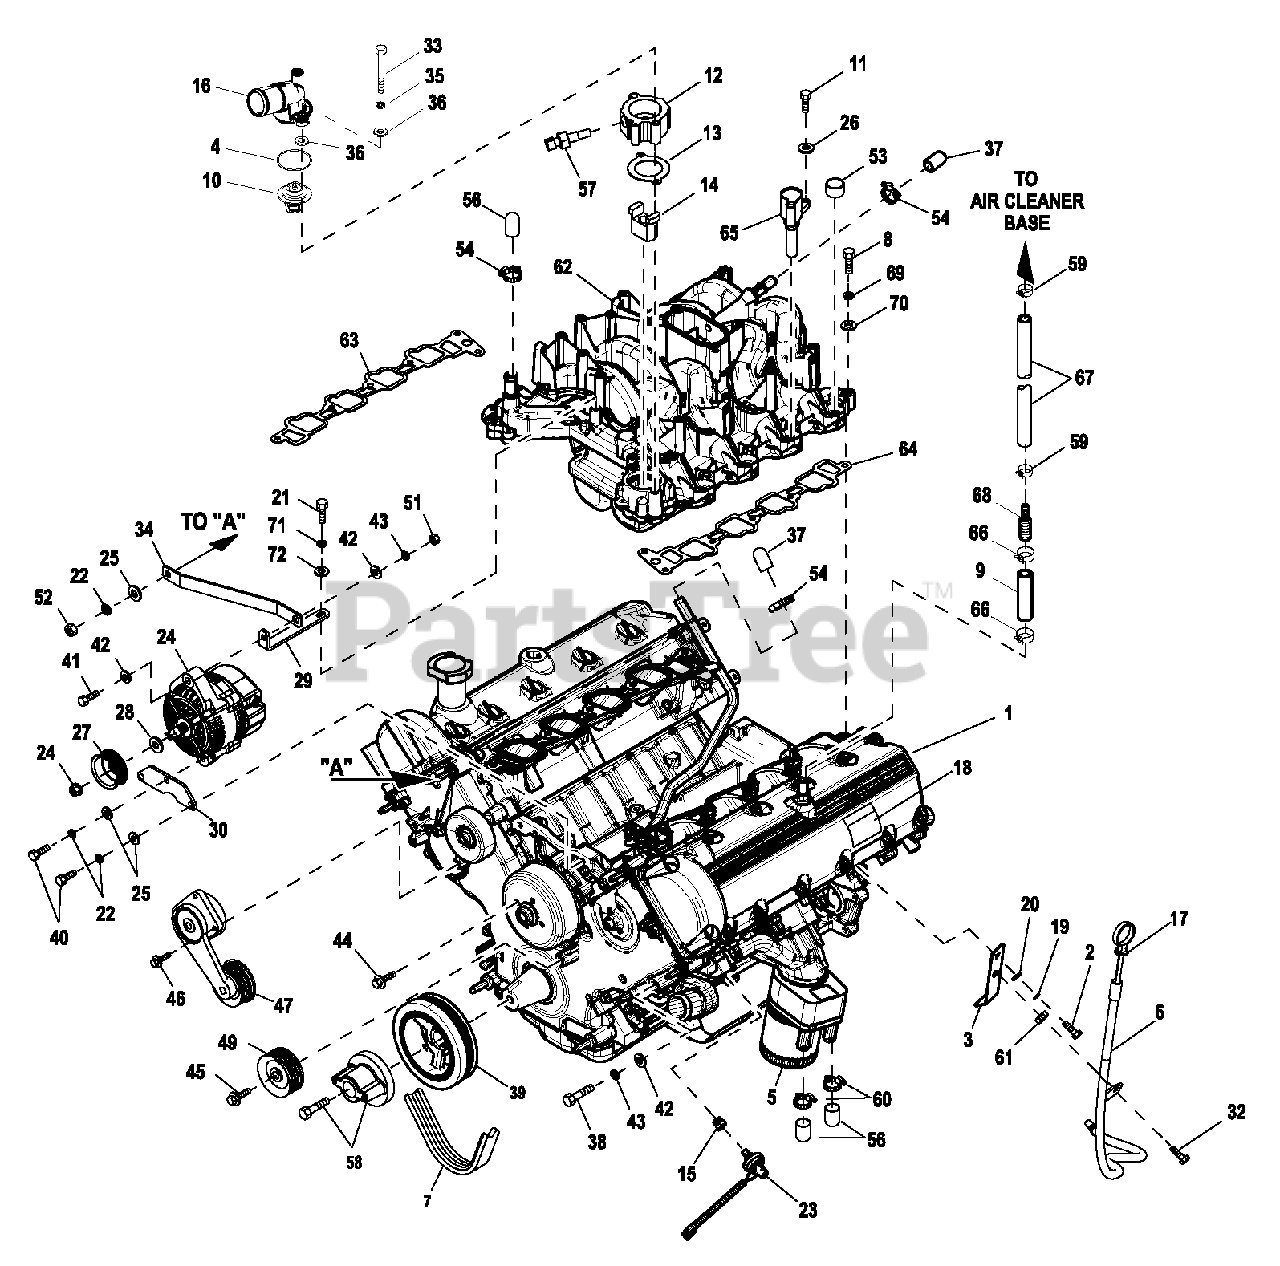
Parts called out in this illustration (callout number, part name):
1	5.4L G3 - LONG BLOCK
2	SCREW HHC M6-1.0X20 C8.8
3	BRACKET DIPSTICK TUBE
4	GASKET THERMOSTAT HOUSING
5	OIL FILTER V-10 ENGINE
6	TUBE DIPSTICK
7	BELT SERPENTINE 65.3" (2650 RPM)
8	SCREW HHC M8-1.25X50 C8.8
9	HOSE COOL 5/8"ID 250#WP (2" LG)
10	5.4L G3 - THERMOSTAT
11	SCREW HHC M5-0.8 X 25 C8.8 BLK
12	ADAPTER THERMOSTAT 4.6L G3
13	GASKET THERMOSTAT 4.2L
14	SPACER COOLANT BYPASS
15	BSHG RD CR HEX 1/4 TO 1/8
16	5.4L G3 - THERMOSTAT OUTLET
17	DIPSTICK
18	D ECAL EPA STATIONARY EMERGENCY
19	WASHER LOCK M6-1/4
20	WASHER FLAT 1/4-M6 ZINC
21	SCREW HHC M6-1.0X20 C8.8
22	WASHER LOCK M8-5/16
23	HARN LOW OIL PRESS SWITCH ASSY
24	ALTERNATOR DC W/OUT PULLEY
25	WASHER FLAT 5/16 ZINC
26	WASHER FLAT M5
27	PULLEY 80 O D DC ALTERNATOR (1800RPM)
28	SPACER D C ALTERNATOR PULLEY
29	BRKT DC ALTERNATOR UPPER
30	BRKT DC ALTERNATOR LOWER
32	SCREW HWHTF M6-1.0X 16
33	SCREW HHC M8-1.25X 140 G8.8
34	BRACKET D C ALT STABILIZER
35	WASHER LOCK M8-5/16
36	WASHER FLAT 5/16-M8ZINC
37	CAP ANTIFREEZE 5/8"ID X 1.2"LG
38	SCREW HHC M10-1.5X60 C8.8
39	REWORK HARMONIC BALANCER 5.4L
40	SCREW HHC M8-1.25X20 G8.8
41	SCREW HHC M10-1.5 X 45 G8.8 FT
42	WASHER FLAT 3/8-M10ZINC
43	WASHER LOCK M10
44	SCREW WP PULLEY M8-1.25 X 19
45	BOLT HEX FLH DM8-1.25X28
46	BOLT HEX FLH DM8-1.25X31
47	TENSIONER ENG. AUTOMATIC BELT
49	PULLEY GROOVE D ENGINE I D LER
51	NUTHEXM10-1.5 G8 YELCHR
52	NUT HEXM8-1.25G8 YELCHR
53	PLUG EXPANSION 14 0 D
54	CLAMP HOSE #10.56-1.06
57	TEMPERATURE SEN DER, DELPHI
58	COUPLING FLEX HUB MACH
59	CLAMP HOSE BAN D .63
60	CLAMP HOSE #12.50-1.25
61	NUT HEX M8-1.25 G8 CLEAR ZIN
62	5.4L G3 - INTAKE MANIFOLD
63	5.4L G3 - INTAKE GASKET RH
64	5.4L G3 - INTAKE GASKET LH
65	COIL & BOOT ASY-IGNITION
66	CLAMP HOSE BAN D .88"
67	HOSE 3/8 ID SINGLE BRAID (14.75" LG)
68	HOSE BARB REDUCER 5/8"-3/8"I D
69	WASHER LOCK M8-5/16
70	WASHER FLAT 5/16 ZINC
71	WASHER LOCK M6-1/4
72	WASHER FLAT 1/4-M6 ZINC
